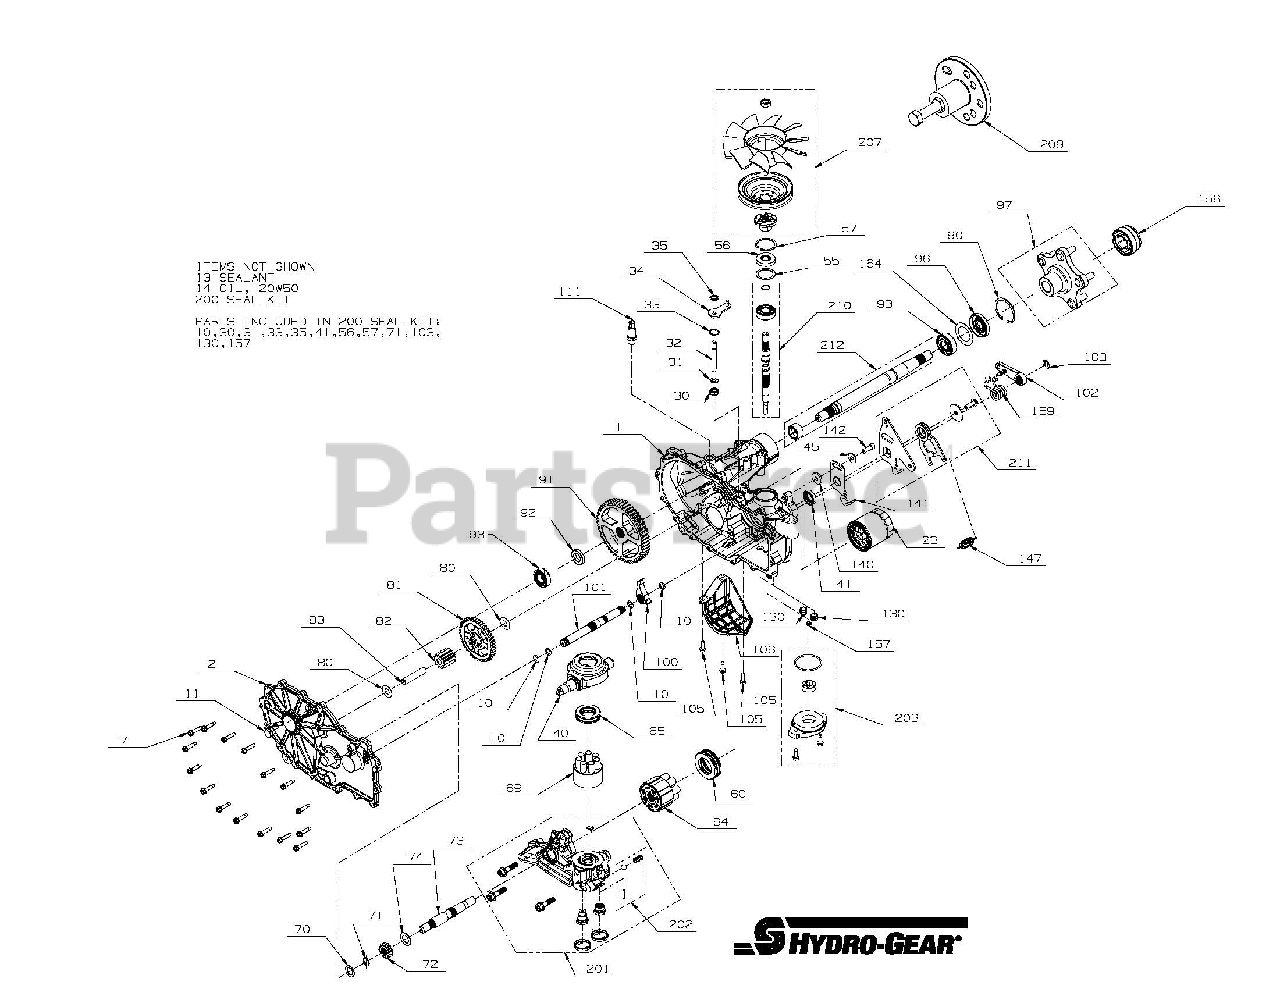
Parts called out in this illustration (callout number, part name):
7	SCREW, HEX WASHER
13	TUBE, SEALANT
23	FILTER, SPIN-ON 2.6 X 3.0
30	SEAL, LIP .375 X .75 X .25
31	RING, RETAINING EXTERNAL .375
33	RING, RETAINING .750, INTERNAL
34	ARM, BYPASS
35	RING, RETAINING .375 EXTERNAL
40	SWASHPLATE, TRUNNION
41	SEAL, LIP 15 X 32 X 7
45	WASHER .34 X .88 X .06
55	WASHER, FLAT 1.23 X 1.57 X .04
56	SEAL, LIP 17 x 40 x 7
57	RING RETAINING INTERNAL
60	BEARING, THRUST- 35 x 62 x 18
64	KIT, 16cc CYLINDER BLOCK ASSEMBLY
65	BEARING, THRUST- 30 x 52 x 13
69	KIT, BLOCK 7 PISTON
70	WASHER, .63 X 1.00 X .05 FLAT
71	RETAINING RING, MOTOR SHAFT
74	WASHER, .71 X 1.16 X .04 FLAT
80	WASHER, .51 X 1.00 X .03 FLAT
83	PIN, JACKSHAFT
90	RING, RETAINING 2.25 INTERNAL
96	SEAL, LIP, TC4, 1.0 X 2.06 X .35
97	KIT, HUB - 5 BOLT
102	KIT, LEFT HAND BRAKE ARM
105	SCREW, HEX WASHER 1/4-20 X .75
106	GUARD, VILER, LH
111	KIT, FITTING 1/2 BEADED 9/16 SAE
140	SPACER 0.320 ID X 1.005 OD X 0.1495 THK
141	ARM, RETURN LEFT
142	SHCS 5/16-24 x 7/8
147	SPRING, EXTENSION
200	KIT SEAL, ZT-2800
203	KIT CHARGE
207	KIT FAN/PULLEY
209	KIT HUB PULLER
210	KIT INPUT SHAFT
211	KIT, RTN CCW
